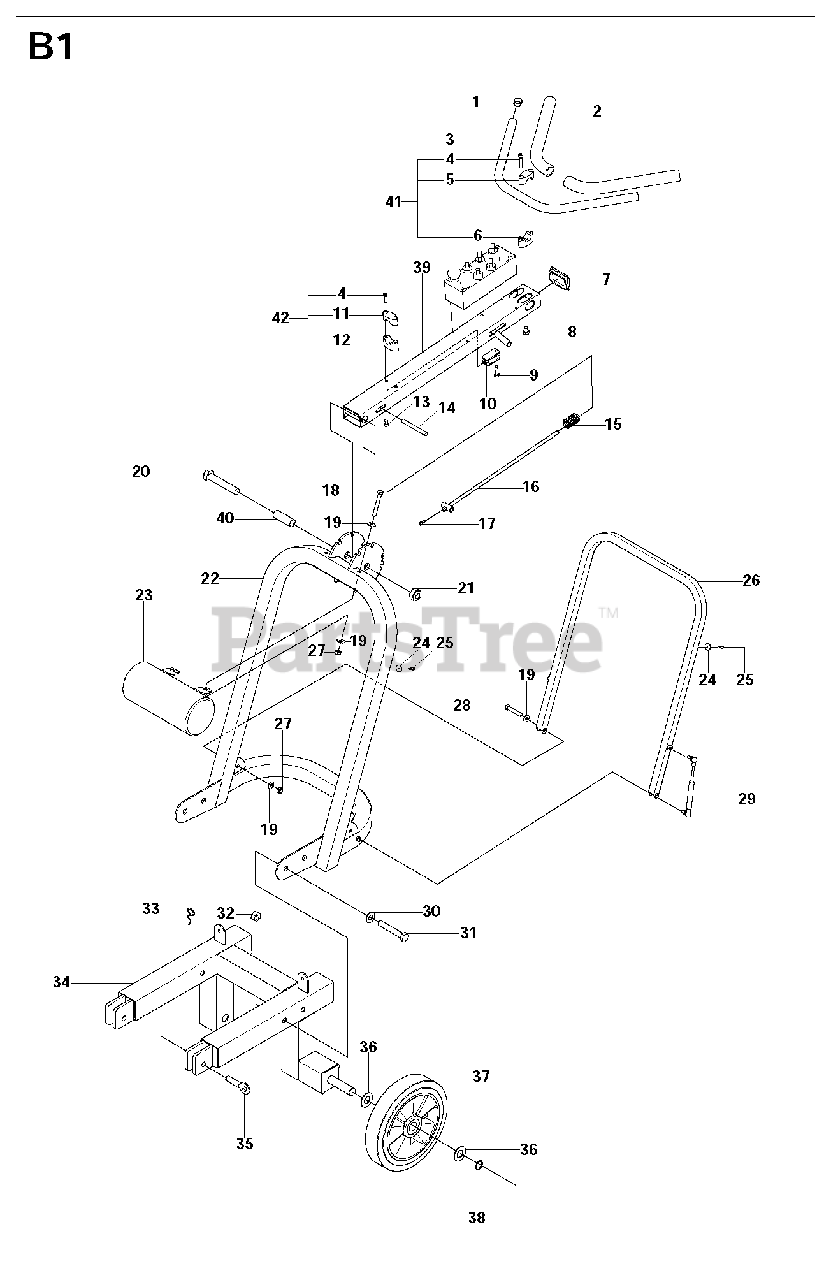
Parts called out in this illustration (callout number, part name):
19	WASHER
27	HEXAGON LOCKING NUT
33	SPRING COTTER
